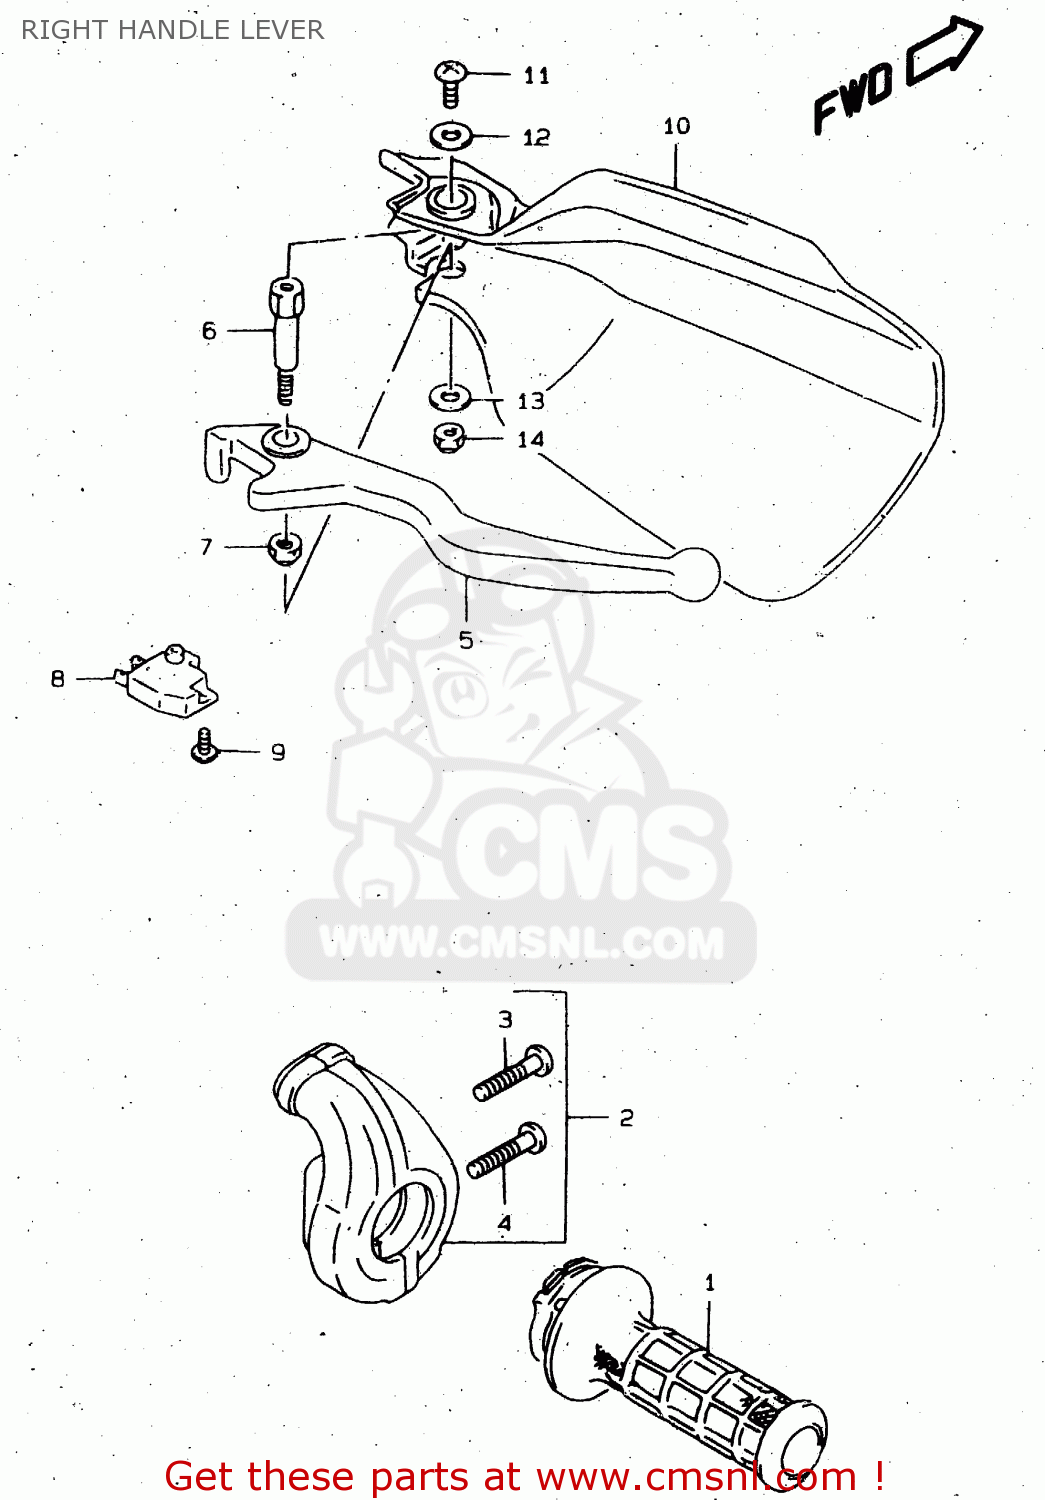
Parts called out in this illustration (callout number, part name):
1	GRIP,THROTTLE
2	CASE ASSY,THROTTLE
3	SCREW(5X25)
4	SCREW
5	LEVER,BRAKE
6	BOLT,BRAKE LEVER PIVOT
7	NUT
8	SWITCH ASSEMBLY,STOP
9	SCREW
10	COVER,KNUCKLE,R
11	SCREW
12	WASHER(5.5X16X1.2)
13	WASHER(6.5X16X1.6)
14	NUT 6MM
